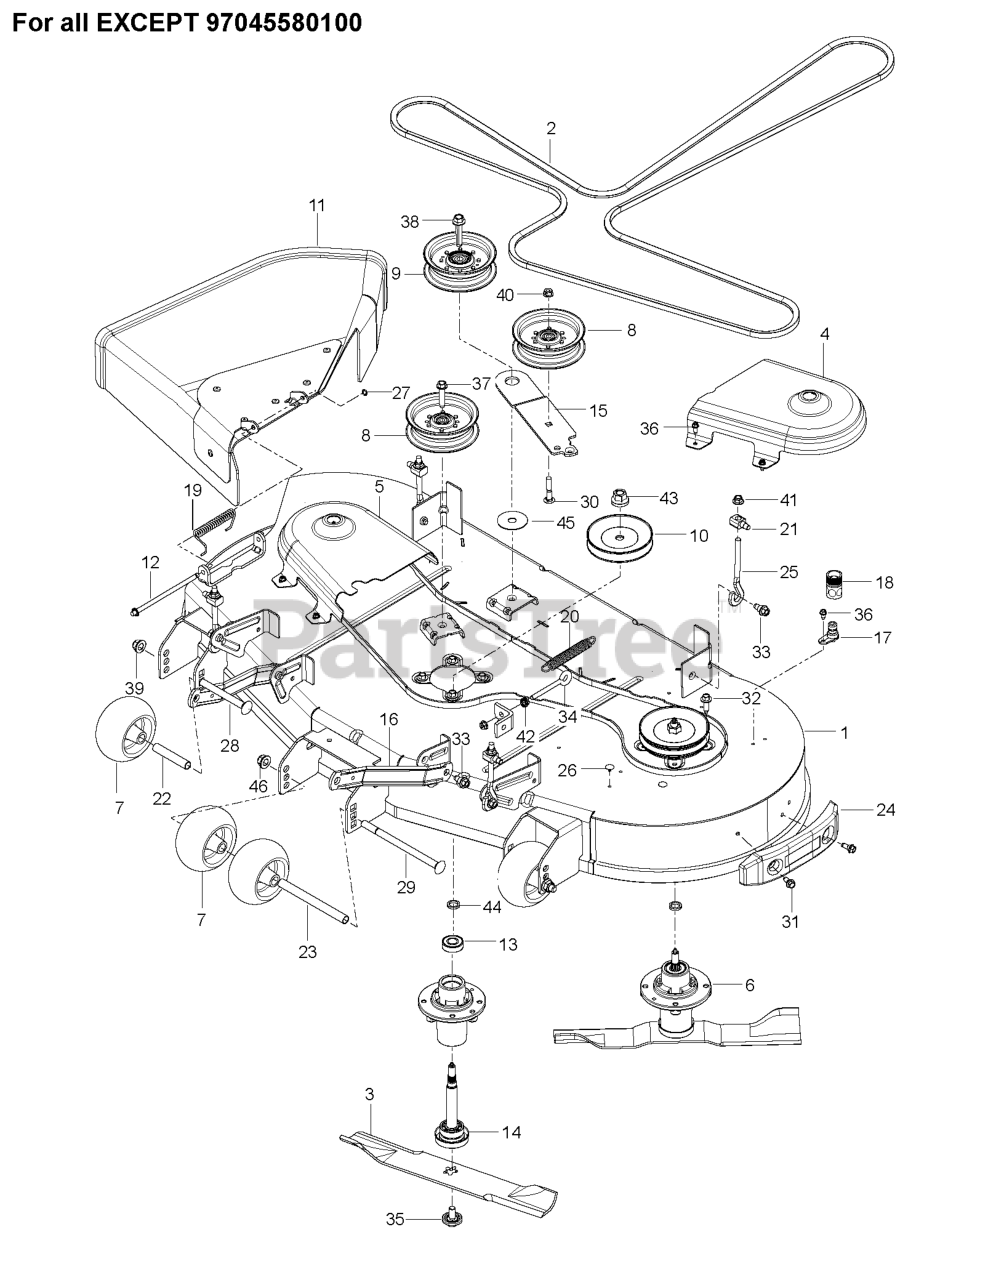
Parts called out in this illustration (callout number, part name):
1	DECK.SVC.54.CLRCT.MZ.MS668
2	BELT CLEARCUT 54, MZ DECK DRIV
3	BLADE CC54 PZ STYLE HI LIFT BL
3	BLADE.54CC.HI-LIFT.PZ.197".431
4	COVER.PNT.54CC.MNDRL.LH.ZTR.GY
4	COVER 54 CLEARCUT, LH MANDREL,
5	COVER 54 CLEARCUT RH MANDREL G
5	COVER 54 CLEARCUT RH MANDREL O
6	MANDREL ASM, CAST IRON
6	MANDREL.DECK.ASSEMBLY
7	ROLLER, GAUGE .635 BORN
8	PULLEY.IDLER.2006
9	PULLEY.IDLER.MWR.STATI.LH
10	PULLEY.MANDREL.CRD 107CM.DOM.
11	DEFLECTOR ASSY 54 CLEARCUT RES
12	ROD.HINGE
14	SHAFT ASM MANDREL
15	ARM IDLER ARM, CLEARCUT 54 BLA
16	ARM.RFIXED.MOWER.SUSPNSIONX431
17	PORT.WASHOUT
18	COUPLING.QUICK CONNECT
19	SPRING.42.FCS.DEFLECTOR
20	SPRING.MOWER.DRIVE.ELECTRIC
22	TUBE, ROLLER AXLE
23	TUBE, ROLLER AXLE LONG
24	BUMPER ASSY 54 CLEARCUT TRIM S
25	LINK.ASM.ADJUSTABLE
25	NUT NUT.3/8-16.HEX.JAM.Z 3/8-1
25	LINK.ADJUSTABLE
26	PLUG CHRISTMAS TREE
27	NUT PUSH M
28	RHSNB 1/2-13 X 4.75 GR5 ZD
31	SHOULDER BOLT 5/16-18TT
32	BOLT.HEX.WASHR.HED.313-18X1.19
33	BOLT.SHOULDER
34	EYE BOLT 5/16 X 3.50
35	BOLT.WASHER.ASM.7/16-2
36	SCREW.1/4-20X5/8
37	SCREW LT
38	SCREW.7/16-14 X 2.125.WASHER
39	NUT, 1/2-13 HEX FLG NYLOC ZD
40	NUT.HEX.FLANGE.3/8-16.LOCKNUT
41	NUT.FLANGE.LOCK
42	NUT 5/16C WHIZ
43	NUT.FLANGE.LOCK.TOP
44	WASHER.SPACER.MANDREL
46	NUT, 1/2-13 HEX FLG NYLOC ZD
